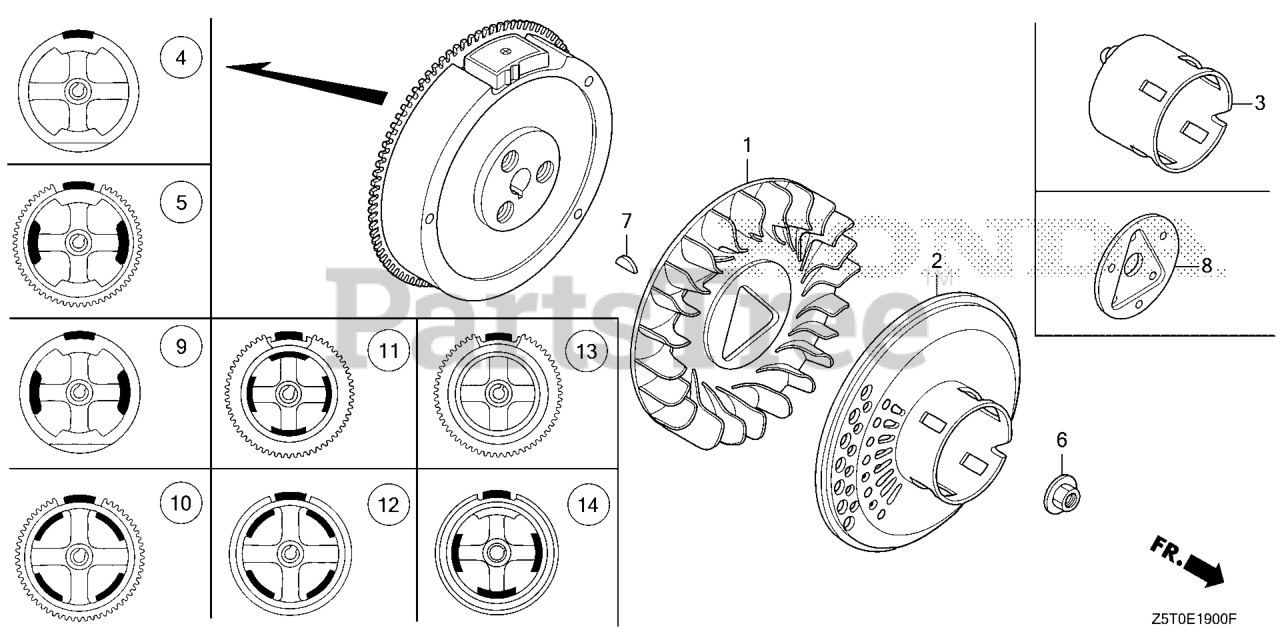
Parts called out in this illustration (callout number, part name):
1	FAN, COOLING
3	PULLEY, STARTER
6	NUT, SPECIAL (16MM) (1)
7	KEY, SPECIAL WOODRUFF (25X18)
10	FLYWHEEL (SEL-4POLE)
